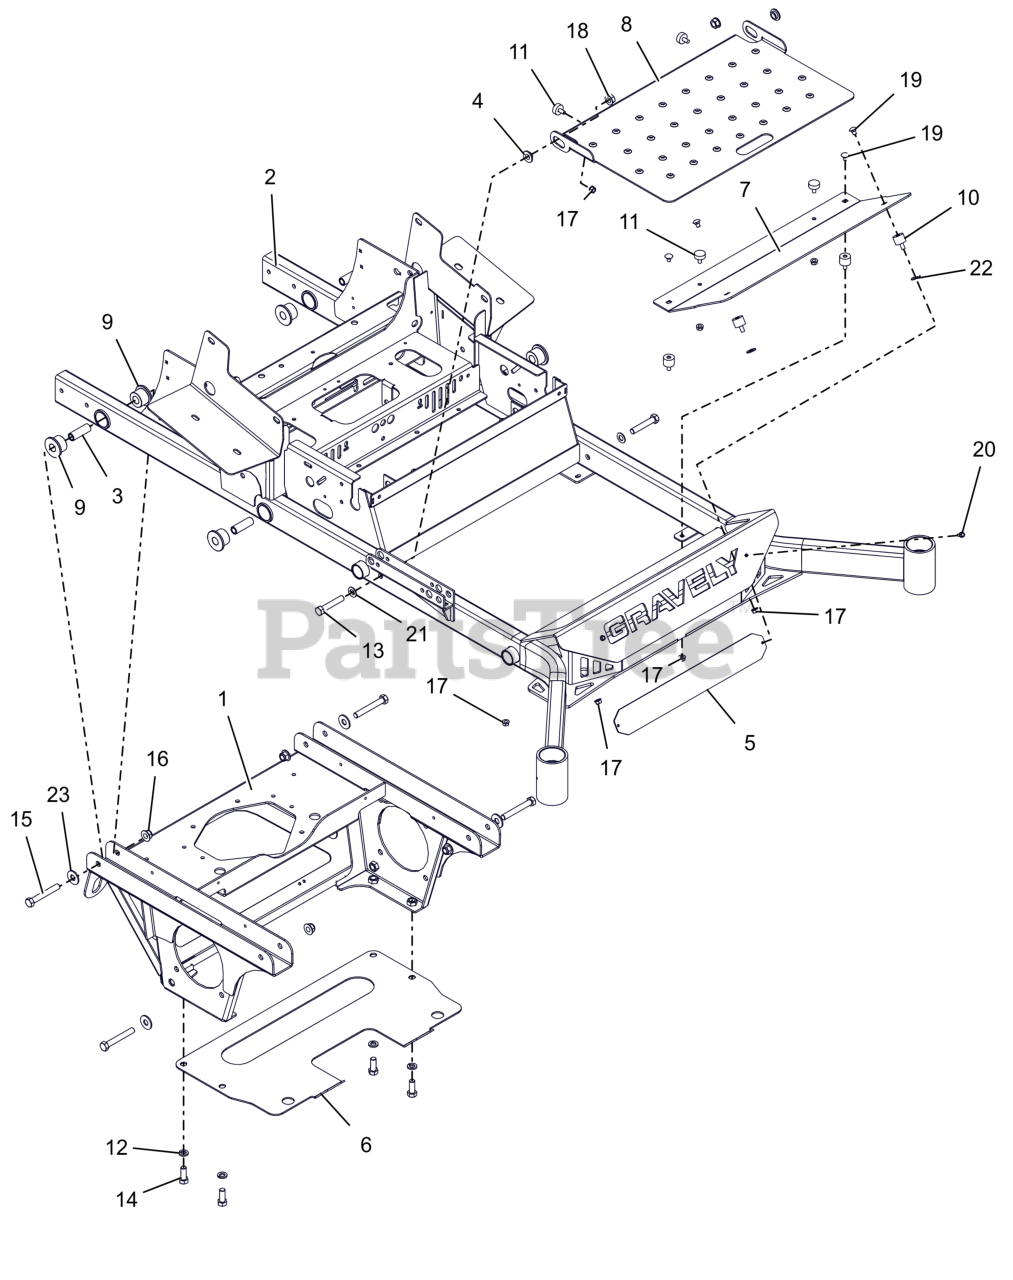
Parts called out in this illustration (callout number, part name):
1	PT200/400 AXLE/ENG FRM WMT-RED
2	72" PT200/400 FRAME W/DECALS
3	BSHG-SLV .50X.75X2.23
4	BSHG-FLG .515X.750X.310X1.120
5	BUMPER LOGO BACKING PLATE -BLK
6	PLATE-TRANSMISSION SKID
7	FOOTREST, (RED)
8	INSPECTION PANEL W/SAFE DECAL
9	BSHG-FLG .75X1.51X1.13X2.0 URE
10	BUMPER,STUD MNTD W/FEMALE INSR
11	BUMPER, RUBBER
12	WSHR,LK-REG .500X.125 ZCC
13	BLT,HEX .50-13X2.75 G5 ZCC
14	BLT,HEX .50-13X1.25 G5 ZCC
15	BLT, HEX .50-13X3.50 G5 ZCC
16	NUT,NYL-FLG .50-13 GF ZCC
17	NUT,SPNLK-FLG .31-18 G5 ZCC
18	NUT-LK-CTR-FLG .500-13 GG ZCC
19	BTL,RHSN .313-18 X 0.5 G5 ZCC
20	SCR-TAP .25-20X.50 HWH ZCC
21	WSHR, FLT .531X1.00X.063 ZCC
22	WSHR,FLT .375X.875X.083 ZCC
23	WSHR,FLT .563X1.375X.109 ZCC
